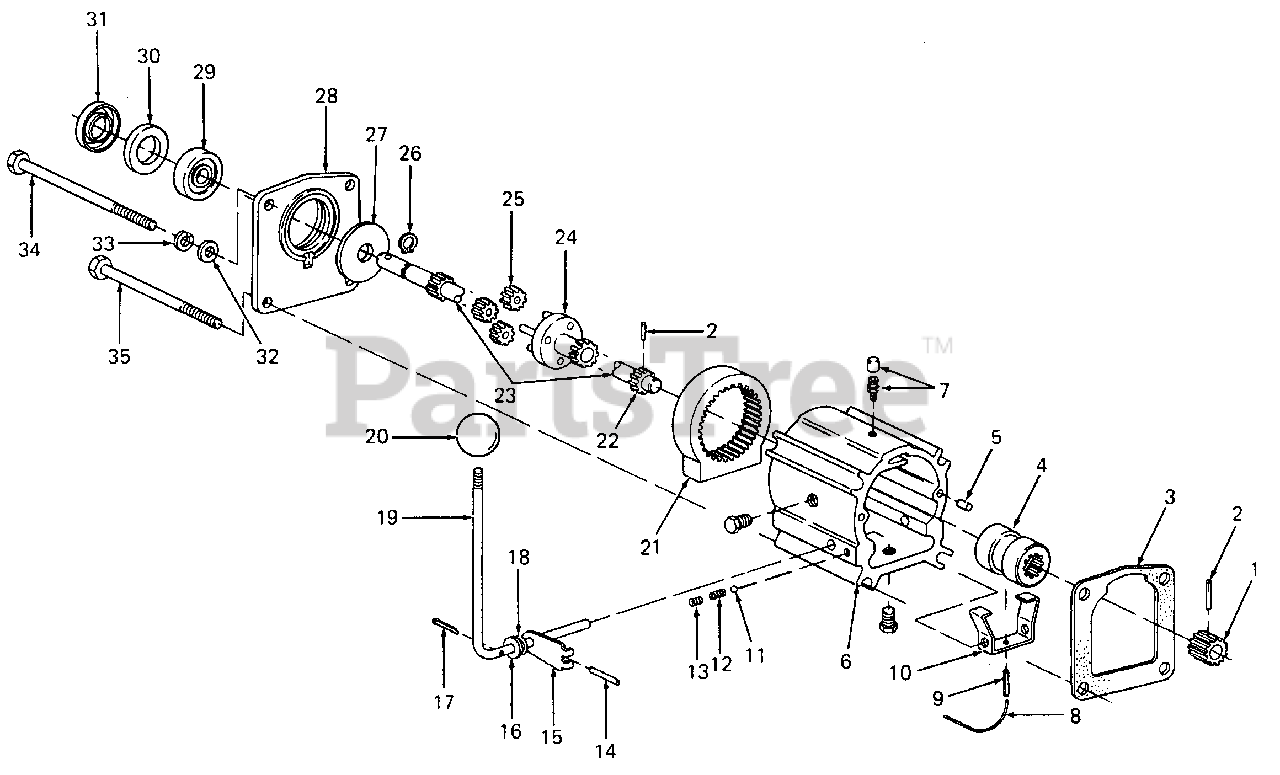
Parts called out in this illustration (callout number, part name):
1	Coupling, Driven
2	Pin, Spiral Spring, 1/4 Dia X 7/8 Lg
4	Collar, Shifter
5	Pin, Dowel, 1/4 Dia X 3/4 Lg
6	Housing, Creeper
8	Wire, .062 Dia X 4.0 Lg
9	Pin, Roll, 3/16 Dia X 3/4 Lg
10	Yoke, Shift
11	Ball, Detent
12	Spring, Detent
13	Screw, Set, 5/16-18 X 1/4 Lg
14	Pin, Roll, 3/16 Dia X 1-5/8 Lg
15	Plate, Detent
16	Washer, Flat, .385 X .62 X .03 Thk
17	Pin, Cotter, 3/32 Dia X 5/8 Lg
18	O-Ring, 3/8 OD X .06 Thk
19	Lever, Shift
20	Knob
21	Race, Planetary
22	Coupling, Direct Drive
23	Shaft, Input
24	Carrier Assy, Planet
25	Gear, Planet - 12T
26	Ring, Snap, 5/8 Dia
27	Washer, Flat, .937 X 2.50 X .04 Thk
28	Plate, Front
29	Bearing, Ball
30	Spacer, Shaft, 1.25 X 1.50 X .325 Thk
31	Seal, Oil
32	Washer, Flat, .406 X .750 X .063 Thk
33	Washer, Lock, 3/8
34	Screw, Hex Cap, 3/8-16 X 5.0 Lg
35	Screw, Hex Cap, 3/8-16 X 4.5 Lg
